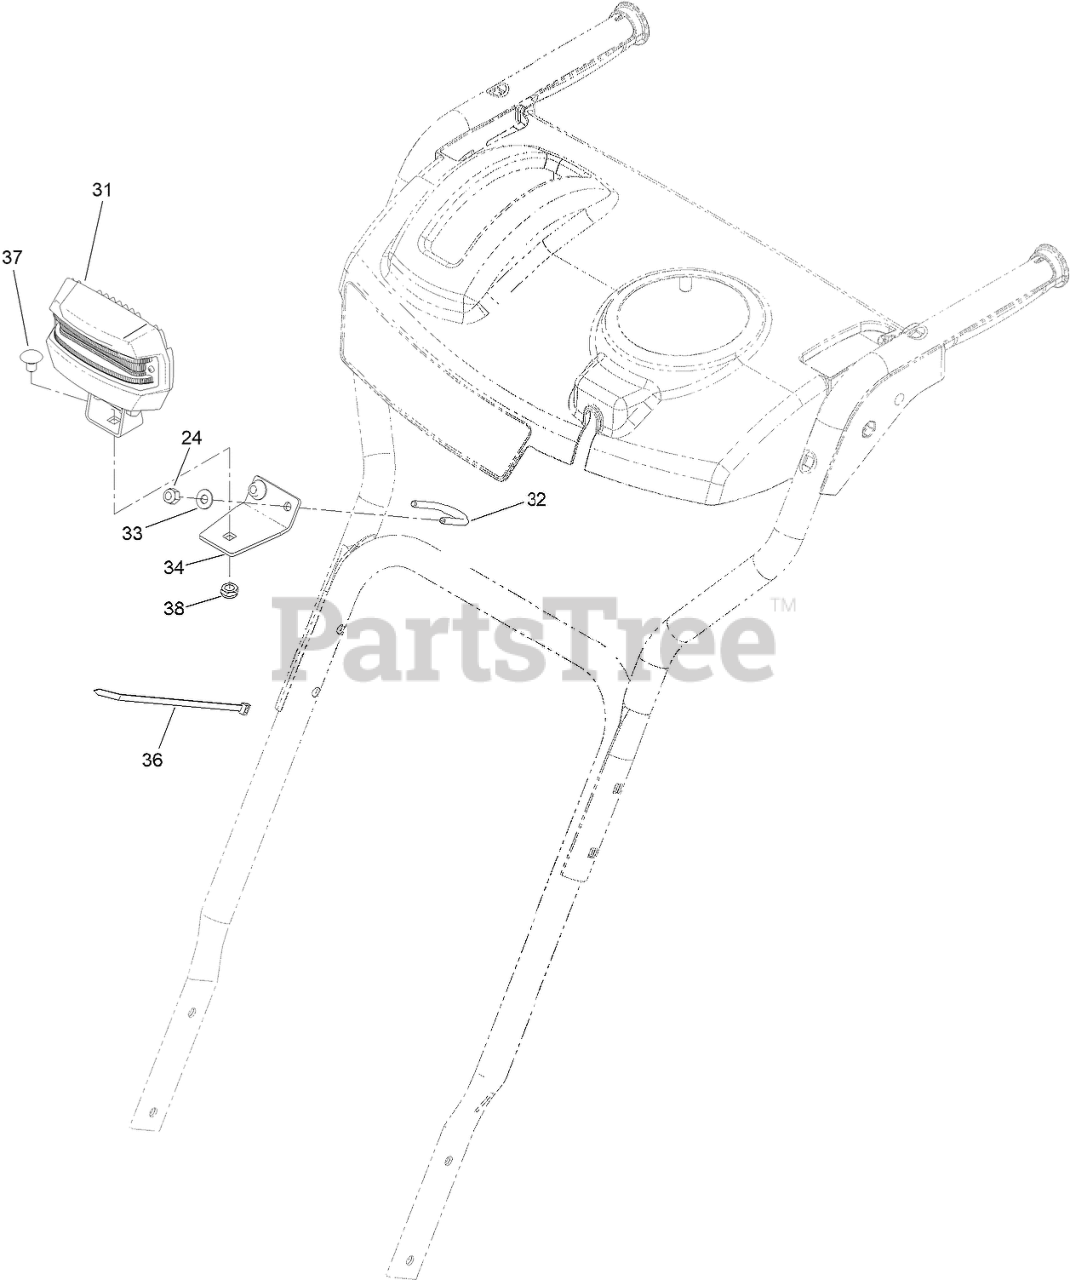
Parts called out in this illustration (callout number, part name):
24	NUT-HEX
31	LED LIGHT ASM
32	CLAMP-LIGHT
33	WASHER-PLAIN
34	BRACKET-LIGHT
36	TIE-CABLE
37	BOLT-CARR
38	NUT-HEX
